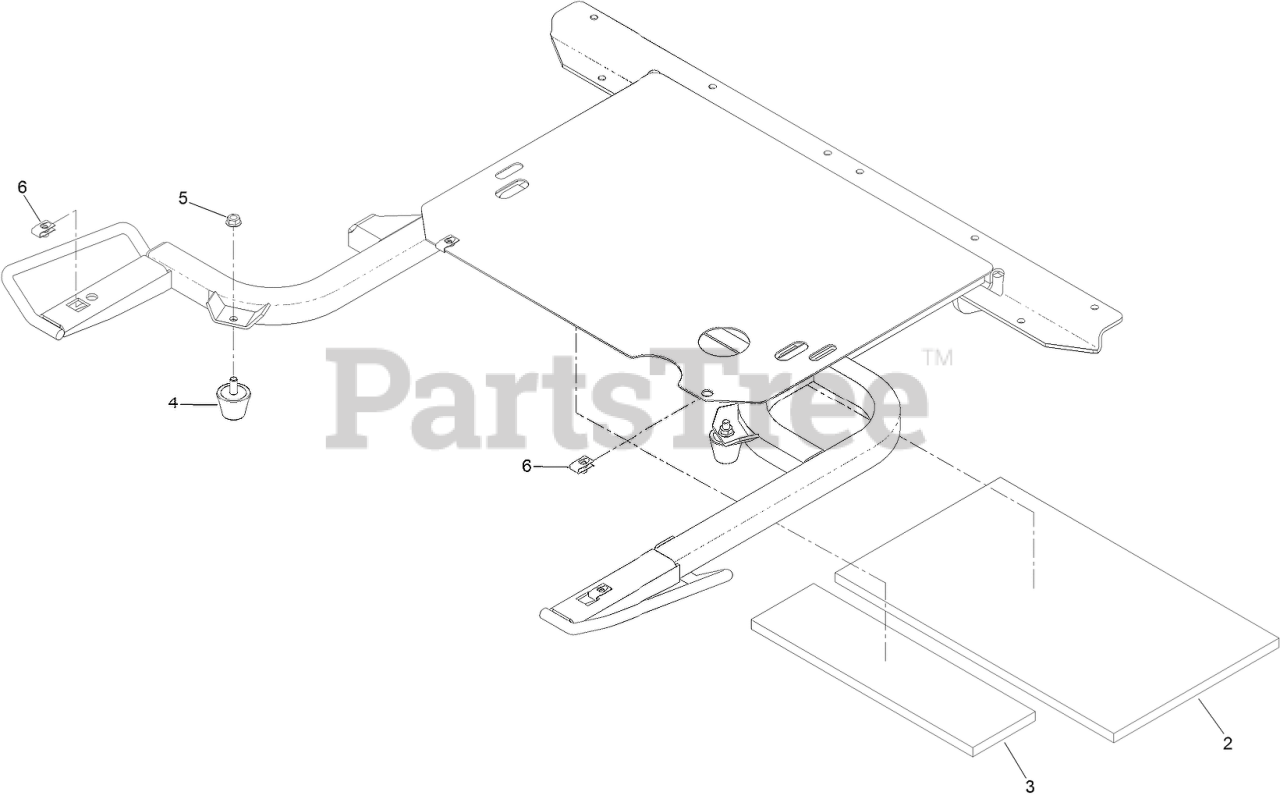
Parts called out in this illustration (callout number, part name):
2	INSULATION-FOAM PAD, REAR
3	INSULATION-FOAM PAD, FRON
4	BUMPER-RUBBER
